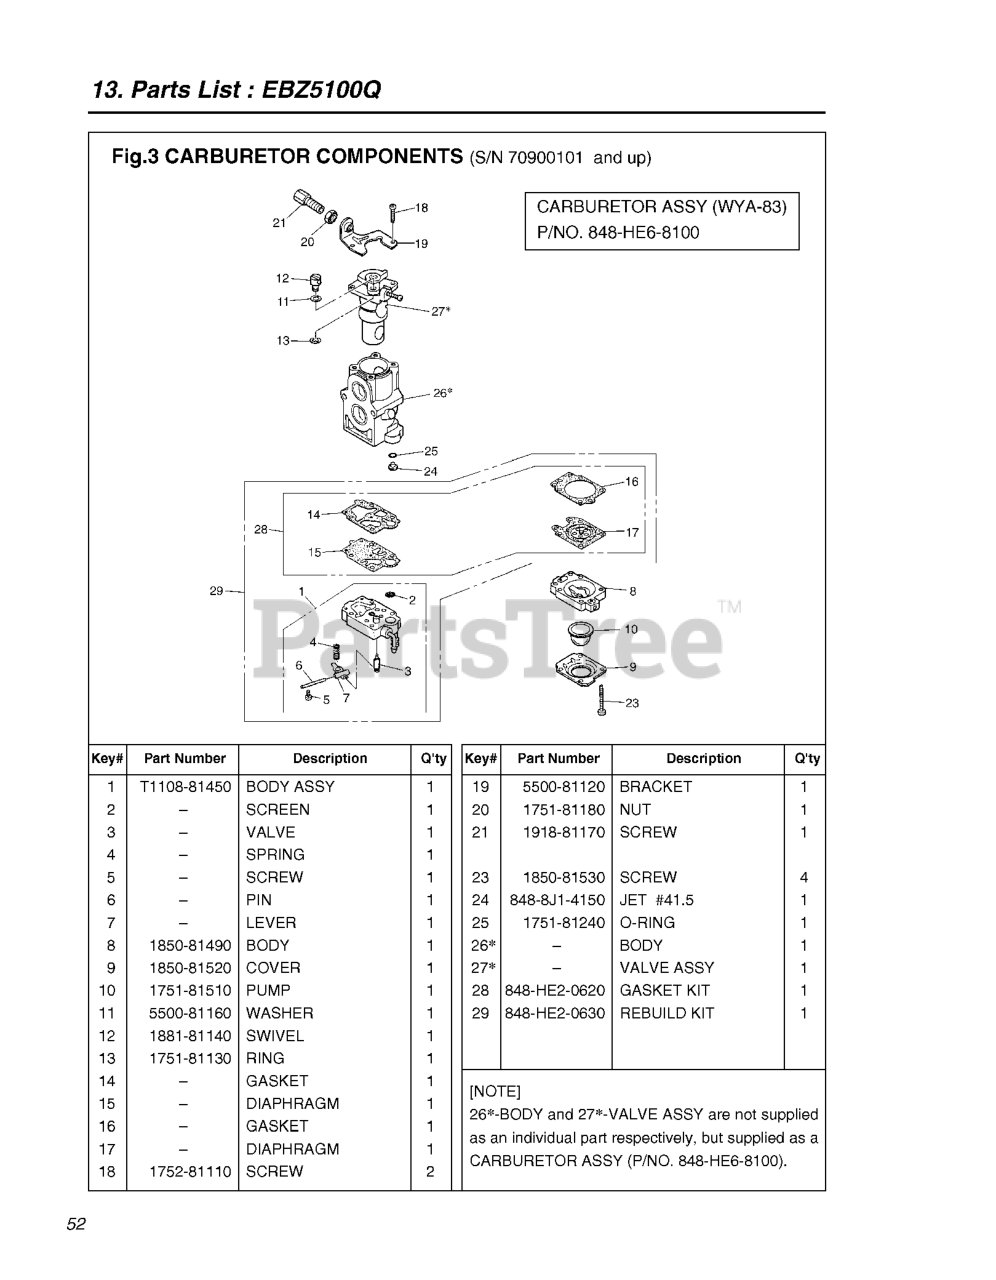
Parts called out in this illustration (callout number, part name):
1	BODY-A-PUMP
9	1OVER
11	WASHER
12	SWIVEL
13	RING
15	DIAPHRAGM
17	DIAPHRAGM
18	SCREW
19	BRACKET
20	NUT
21	ADJUSTER
26	CARBURETOR ASSEMBLY
27	CARBURETOR ASSEMBLY
28	GASKET KIT
29	REBUILD KIT
